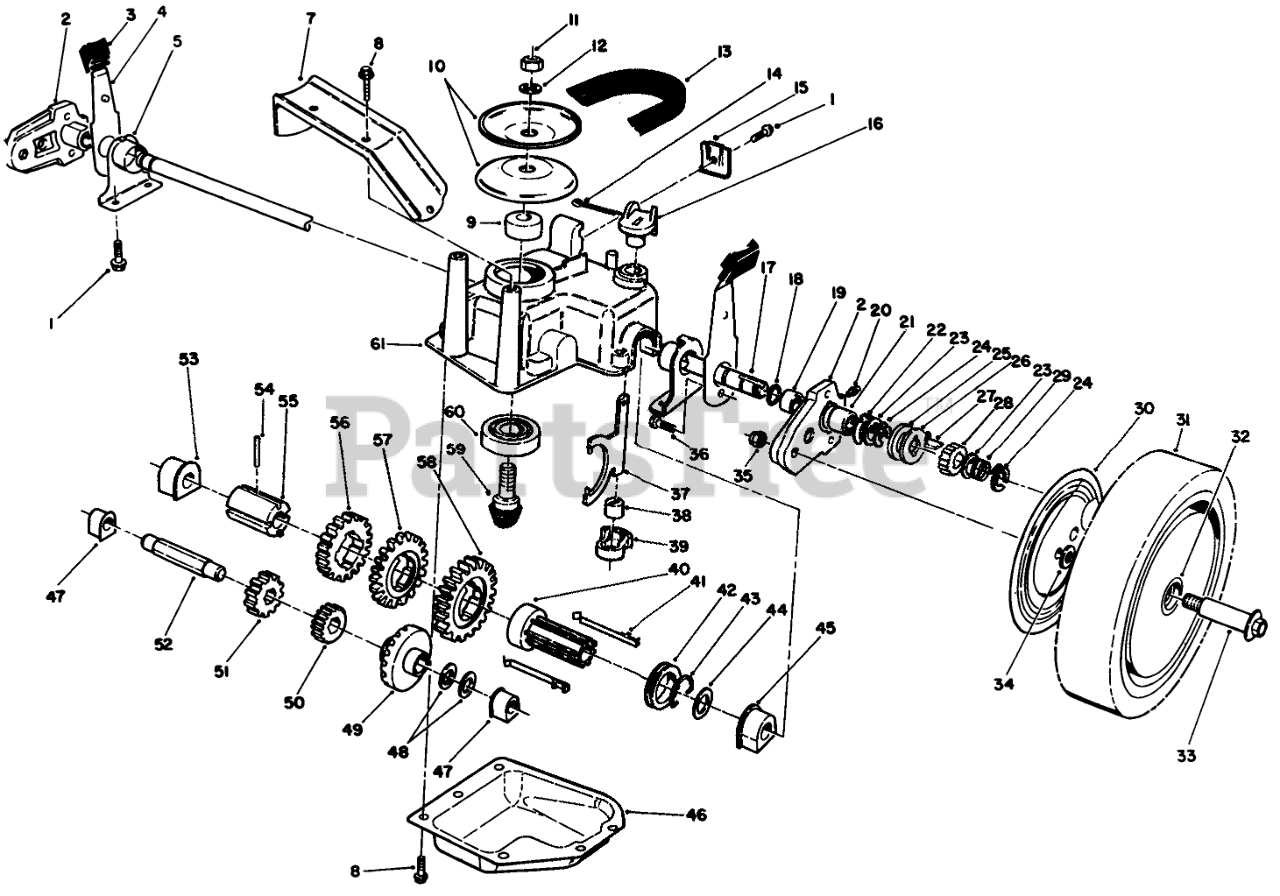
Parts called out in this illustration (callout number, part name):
1	SCREW-HWHTF
2	Pivot Arm Assembly (Incl. Ref. #19-21)
3	KNOB-ARM
4	SPRING ARM ASM
5	CAP-END
7	Bracket-BeltGuide
8	SCREW-HWHTF
9	SPACER
10	Pulley Half
11	NUT-HEX
12	WASHER-FLAT
13	V-BELT
14	PIN-COTTER
15	CABLE CLAMP
16	Lever-Shift
17	SHAFT-OUTPUT
18	O-RING
19	BUSHING
20	FITTING-GREASE
21	BEARING-ROLLER
22	WASHER-ARM, PIVOT
23	WASHER-THRUST, KEYED
24	RING-CLIP, LOCKING
25	RING-FRICTION
26	WASHER-CLUTCH
27	KEY-ROCKING, LH
28	GEAR-PINION
29	SPRING-COMPRESSION
30	WHEEL COVER
31	Wheel Tire & Gear Assy. (Incl. Ref. #32)
32	BUSHING
33	WHEEL BOLT
34	WASHER
35	Nut
36	SCREW-HSH, THREAD FORMING
37	YOKE-SHIFT
38	BUSHING-YOKE
39	RETAINER-FORK, SHIFT
40	Sleeve-Shift Key
41	SHIFT KEY
42	SHIFT COLLAR
43	CLIP-SPRING
44	WASHER-PLAIN
45	BUSHING-OUTPUT
46	Cover-Gearcase
47	BUSHING
48	WASHER-THRUST
49	Gear-Bevel
50	PINION-20T
51	PINION-25T
52	SHAFT-INTERMEDIATE
53	BUSHING
54	PIN-SPRING
55	SLEEVE-GEAR
56	GEAR-39T
57	GEAR-44T
58	GEAR-49T
59	Gear-Pinion
60	BEARING-BALL
61	CASE-GEAR, UPPER
